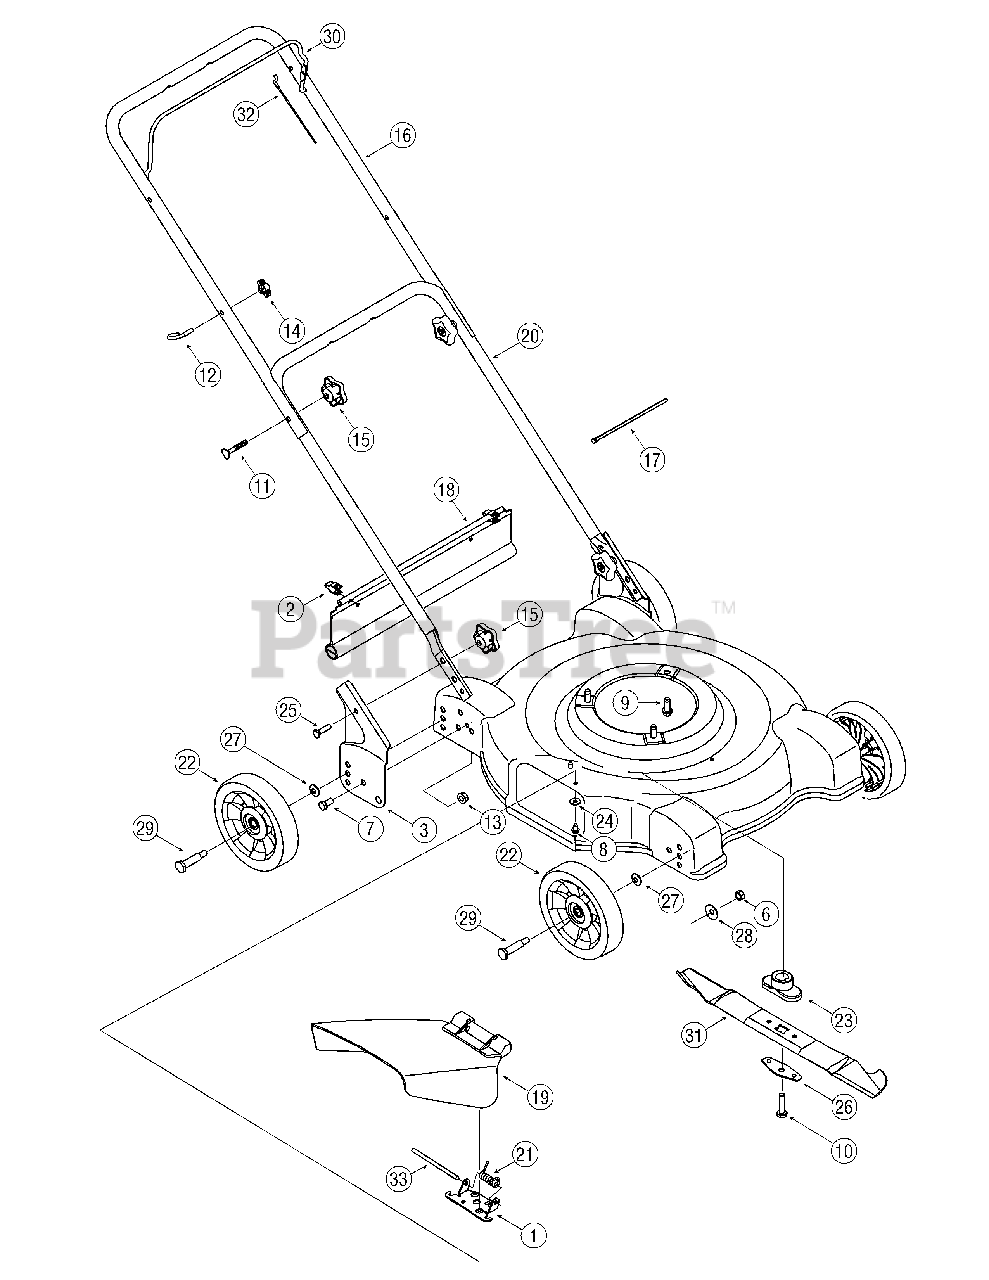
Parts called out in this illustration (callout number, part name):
1	Chute Hinge
2	Hinge Clip
6	Hex Nut, 3/8-16
7	Hex Cap Screw 3/8-16 x .75
8	TT Screw 1/4-20 x 0.5"
9	TT Screw 3/8-16 x 1.0
10	Hex Cap Screw 3/8-24 x 1.5
11	Carriage Bolt 5/16-18 x 2.0
12	Eye Bolt
13	Lock Nut 3/8-16
14	Wing Nut
15	Star Knob
17	Cable Tie
18	Trail Shield
19	Hinged Chute Deflector Assembly
21	Torsion Spring
22	Wheel, 7 x 1.5, Star-Diam
23	Blade Adapter
24	Bell Washer .265 ID x .75 OD
25	Clinch Stud
26	Blade Bell Support
27	Bell Washer, .375 x .870 x .063
28	Bell Washer, .390 x 1.13 x .062
29	Shoulder Screw, .498 x 1.635
31	Standard Blade, 22"
32	Blade Control Cable - 37.25"
33	Hinge Pin
